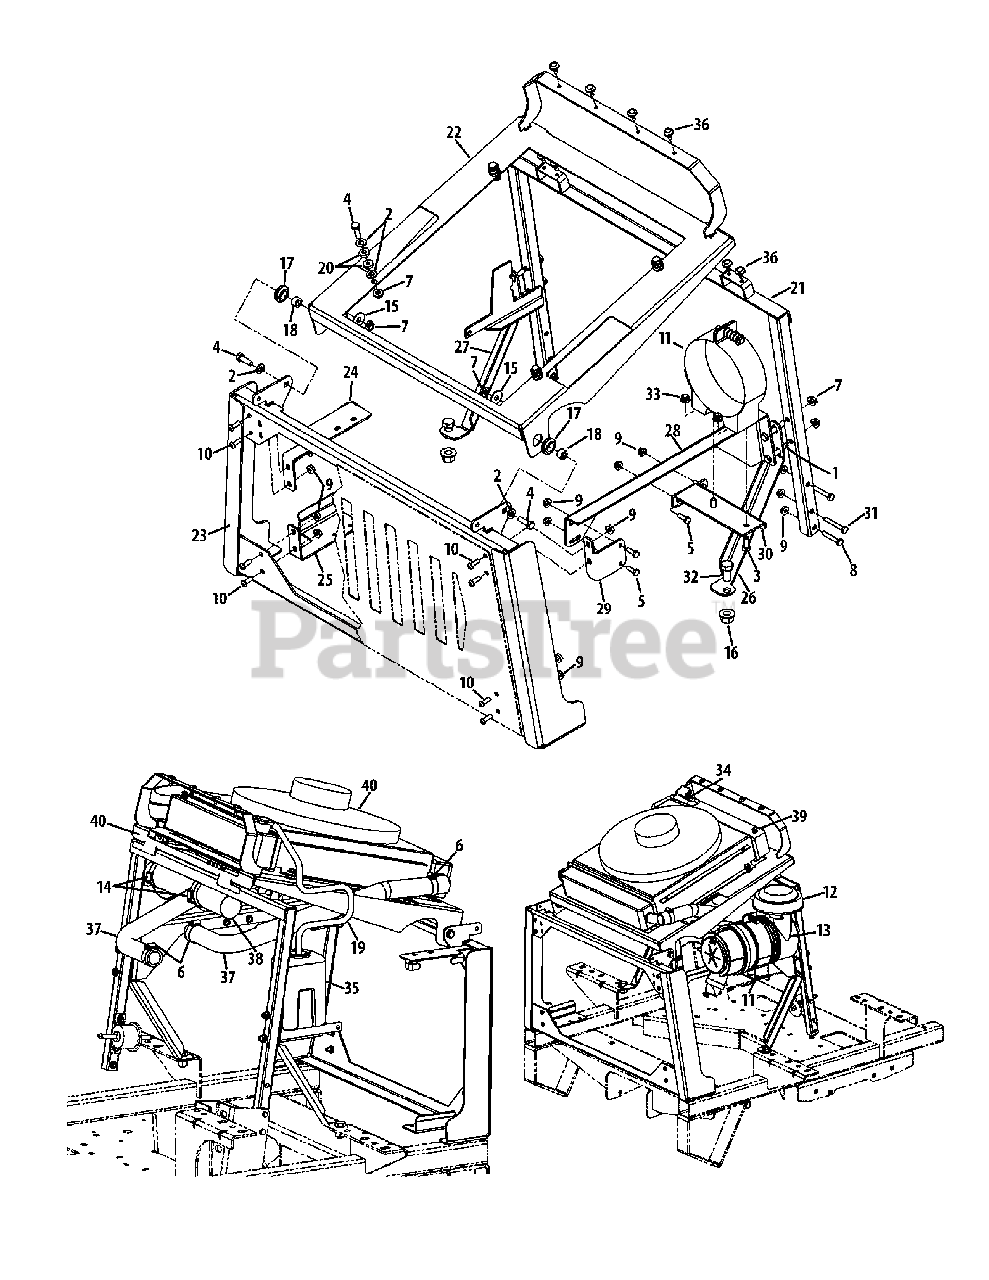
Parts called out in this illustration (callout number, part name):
1	Hex Screw, 5/16-18 x 1.75
2	Washer, .344 x .688 x .063
3	Hex Screw, 5/16-18 x .750
4	Hex Screw, 5/16-18 x 1.00
5	Hex Screw, 1/4-20 x .750
6	Hose Clamp
7	Flange Counter Lock Nut, 5/16-18
8	Hex Screw, 1/4-20 x 1.50
9	Flange Top Lock Nut, 1/4-20
10	Cap Screw, 1/4-20 x .750
11	Air Cleaner Mounting Band
12	Air Cleaner Inlet Hood
13	Air Cleaner Assembly
13	Air Filter
13	Canister, Air Cleaner
13	Cap, Air Cleaner
13	Valve, Dust Ejector
14	Hose Clamp
15	Washer, .313 x 1.06 x .062
16	Flange Top Lock Nut, 1/2-13
17	Grommet, .62 x 1.13 x 1/8
18	Spacer, .357 x .625 x .375
19	Radiator Hose, 1/4 x 27
20	Washer, .280 x .690 x .180
21	Front Radiator Mount
22	Radiator Mount Plate
24	Hydro Cooler Upper Mount Bracket
25	Hydro Cooler Lower Mount Bracket
26	RH Radiator Support Bracket
27	LH Radiator Support Bracket
28	Air Cleaner Support Bracket
29	Air Cleaner Support Bracket
30	Air Cleaner Mount Bracket
31	Hex Screw, 1/4-20 x 1.75
32	Hex Screw, 1/2-13 x 1.00
33	Flange Lock Nut, 5/16-18
34	Hose Clamp, .490
35	Coolant Over-Flow Container
36	Rubber Bumper, .62 x .22
37	Hose, Radiator RH, 29.50"
37	Hose, Radiator LH, 26.50"
37	Hose, 1-1/8" ID, 25 feet Length
38	Hose Air Cleaner, 2" ID, 10" Length
38	Flexible Reinforced Hose " ID
39	Pipe Plug, 1/8-27
40	Radiator, Complete
40	Fan assembly
40	Debris Screen
40	Radiator Cap
